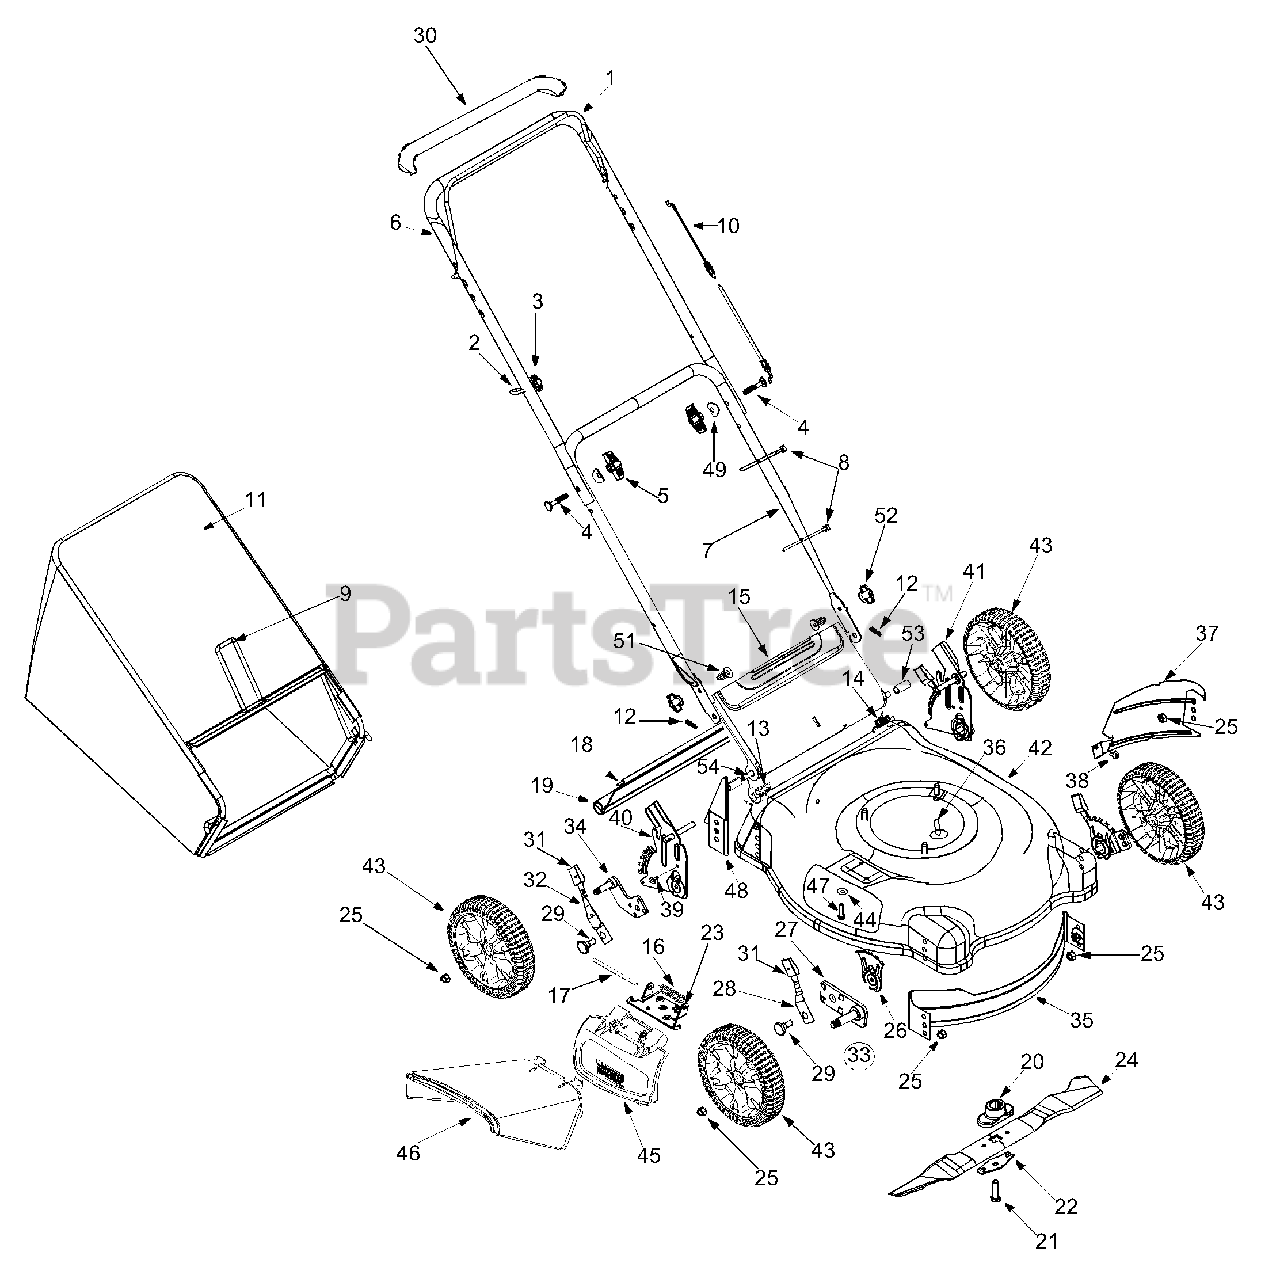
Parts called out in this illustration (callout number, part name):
2	Rope Guide
3	Handle Knob 1/4-20 Thd.
4	Curved Hd. Bolt 5/16-18 x 2"
5	Hand Knob
8	Cable Tie
10	Control Cable
11	Grass Bag
12	Int. Cotter Pin 5/16" Dia.
13	Door Spring - R.H.
14	Door Spring - L.H.
15	Rear Discharge Door
16	Torsion Spring
17	Hinge Pin
18	Wire Rod
19	Rear Flap
20	Blade Adapter w/Star
21	Hex Bolt 3/8-24 x 1.5" Lg.
22	Blade Bell Support
23	Deflector Chute Adapter
24	21" Mulching Blade w/Star
25	Flange Nut 3/8-16 Thd.
26	Height Adj. Plate
27	Pivot Arm Assembly - RH
28	Front Spring Lever
29	Shld. Bolt.5" Dia. x.357"
30	Deluxe Bail Cover
31	Spring Lever Knob
32	Rear Spring Lever
33	Height Adj. Assy. Comp. - RH
34	Pivot Arm R.H.
38	Torx Mach AB-Tap Scr. 1/4 x.62"
39	Hex Ind Wash. Scr. 1/4-20:.625
40	Handle Bracket - RH
41	Handle Bracket - LH
44	Bell Washer 1/4" I.D.
45	Hinged Mulching Plug
46	Side Chute Deflector
47	Hex Hd Self-Tp Scr. 1/4-20 x.5"
49	Shoulder Washer
51	Hex Carriage Screw 1/4-20
52	Wing Nut
53	Spacer,.375OD x.50ID
54	Rear Door Pivot Rod
